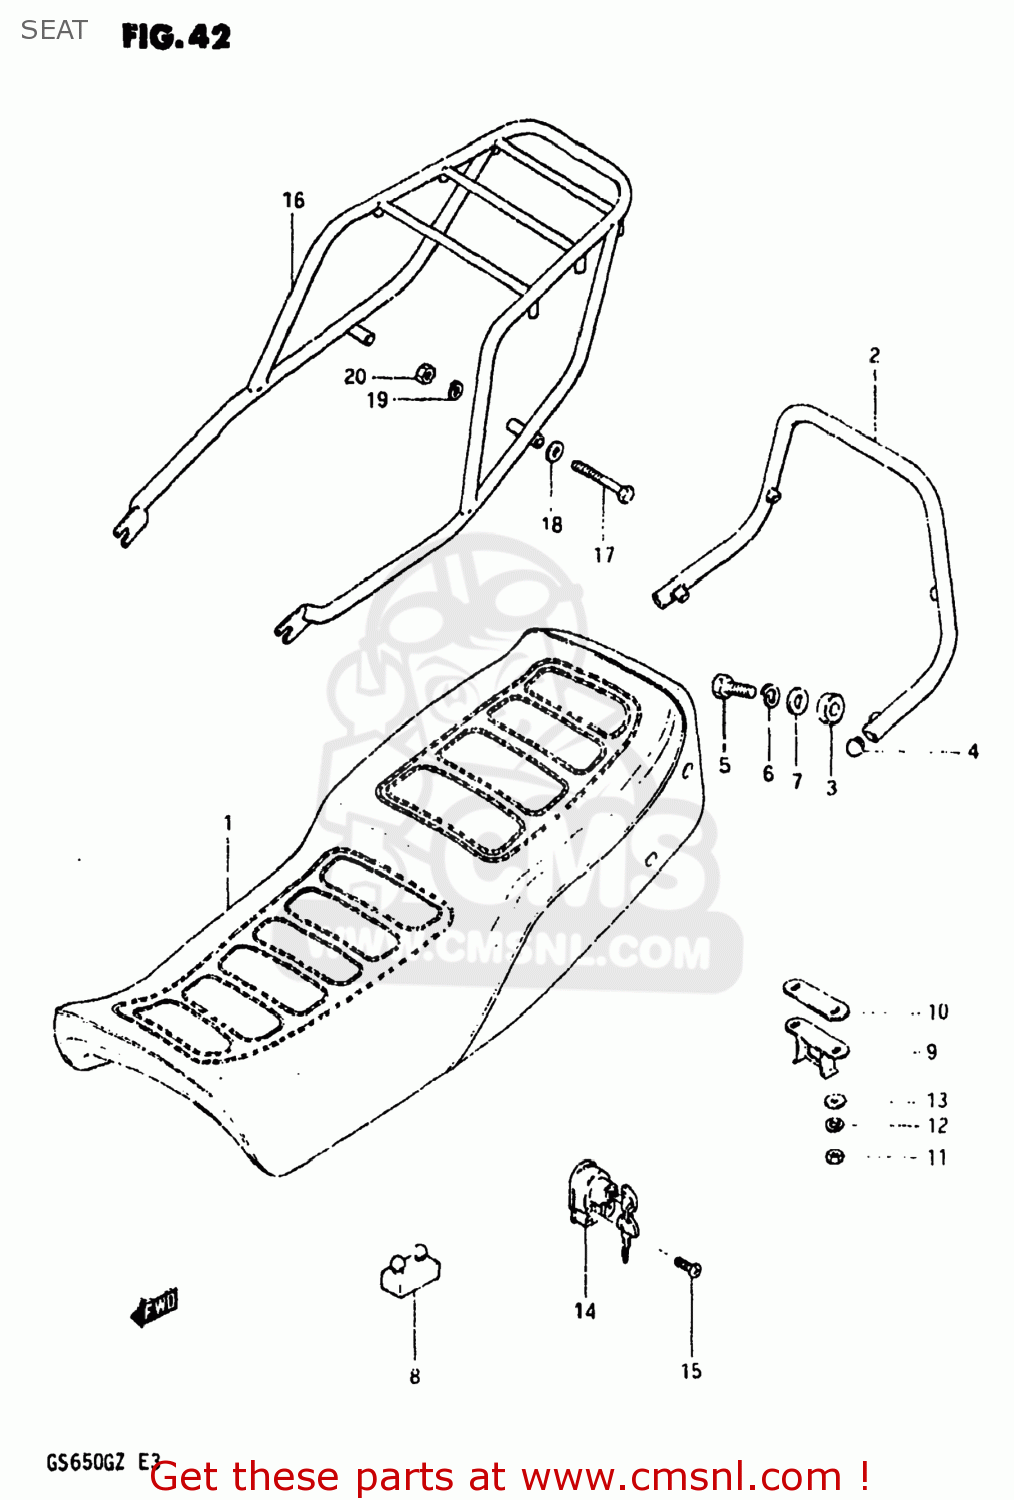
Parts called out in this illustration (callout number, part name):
1	SEAT ASSEMBLY
2	HANDLE,PILLION RIDER
3	CUSHION
4	END,SHEET HANDLE
5	BOLT
6	LOCK WASHER
7	WASHER
8	CUSHION
9	STRIKER,SEAT LOCK
10	SHIM,SEAT LOCK STRIKER
11	NUT 6MM
12	LOCK WASHER
13	WASHER
14	LOCK ASSY,HELMET
15	BOLT 5X25
16	CARRIER
17	BOLT
18	WASHER
19	LOCK WASHER
20	NUT 8MM
